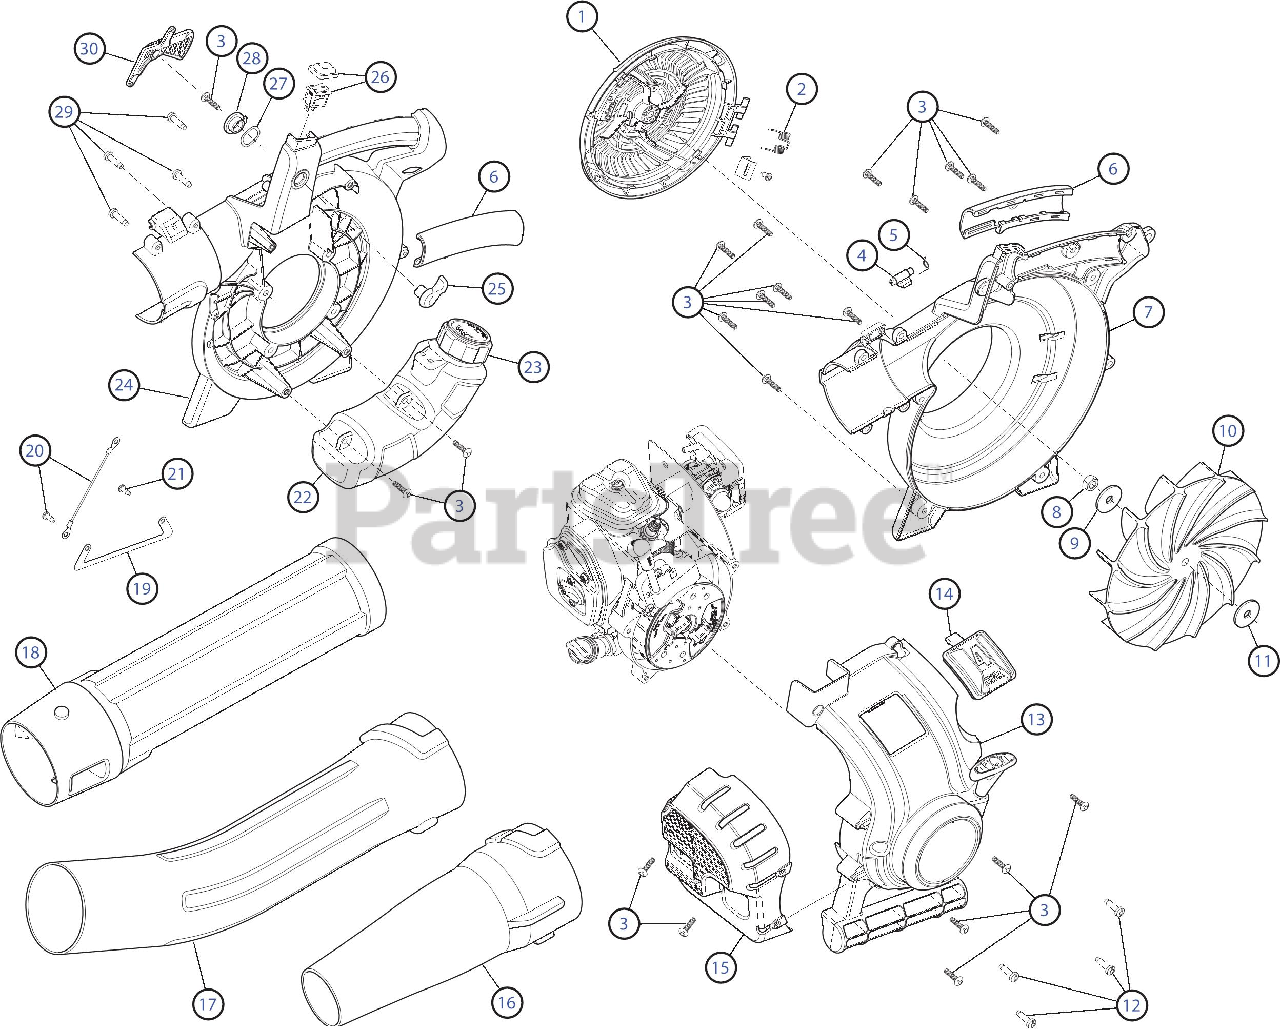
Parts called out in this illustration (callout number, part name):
1	Intake Cover Assembly
2	Spring
4	Latch Tube
5	Latch Spring
6	Handle Grips
7	Impeller Housing
8	Nut
9	Washer
10	Impeller
11	Spacer
13	STARTER HOUSING
14	Spark Plug Cover
15	Muffler Cover
16	Nozzle
17	CURVED LOWER TUBE
18	Upper Tube
19	Strap Ground
20	Wire Ground
21	Screw
22	Fuel Tank Assembly
23	Fuel Cap
24	Impeller Housing
25	Outer Trigger Lock
27	Wavey Washer
28	Inner Trigger Lock
29	Screw
30	Throttle Trigger
